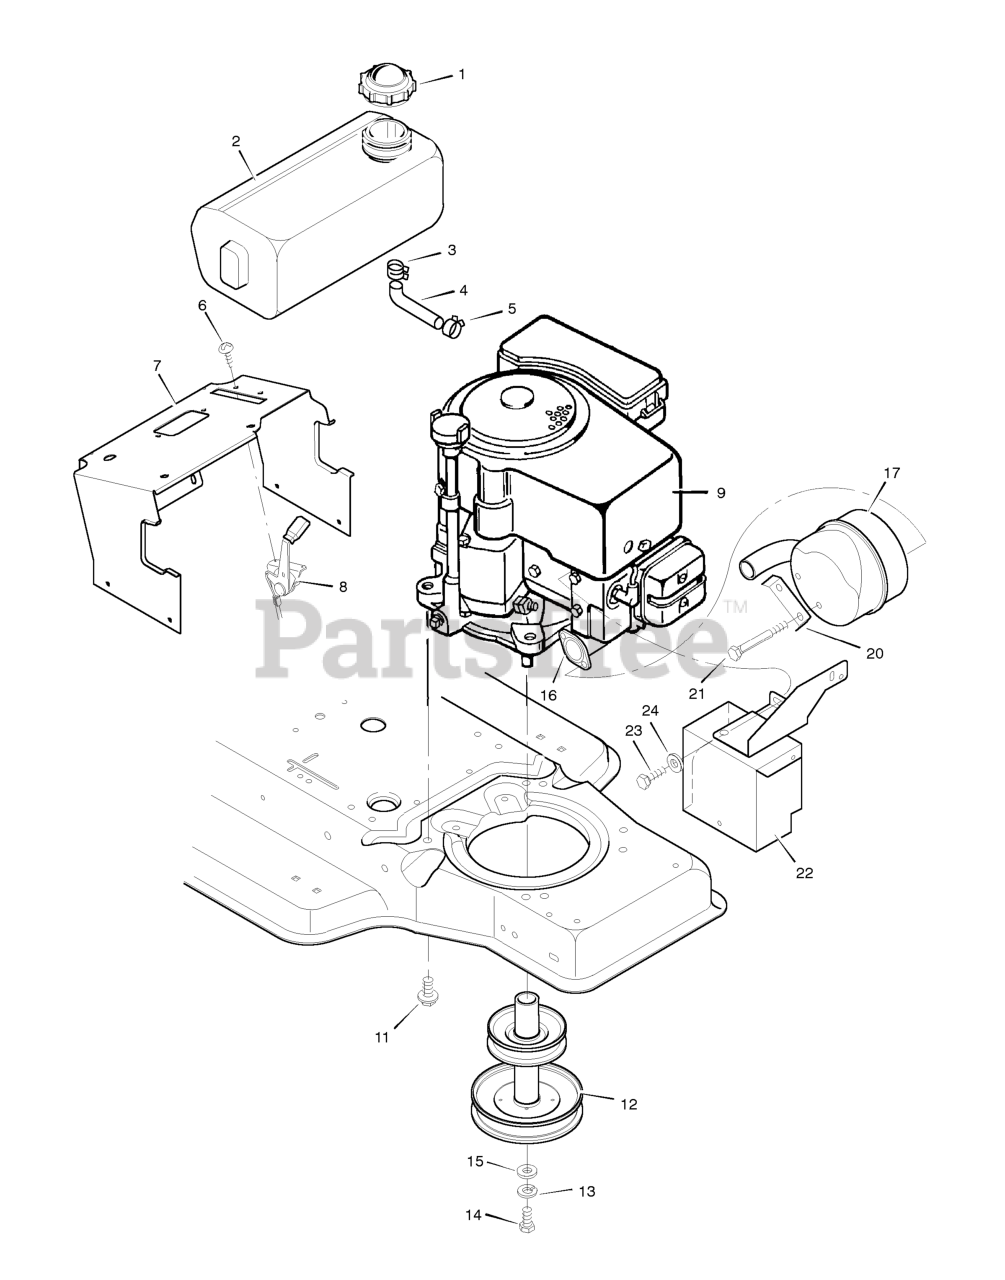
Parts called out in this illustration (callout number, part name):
1	Fuel Cap
2	Fuel Tank
3	Hose Clamp
4	Fuel Line
5	Hose Clamp
7	Support, Dash
8	Throttle Control
9	Engine *
11	Bolt, Engine Mount
12	Stack Pulley Assembly
13	Lockwasher
14	Bolt, Hex
16	GASKET, Exhaust
17	Muffler
20	Lock, Screw
22	Shield, Heat
